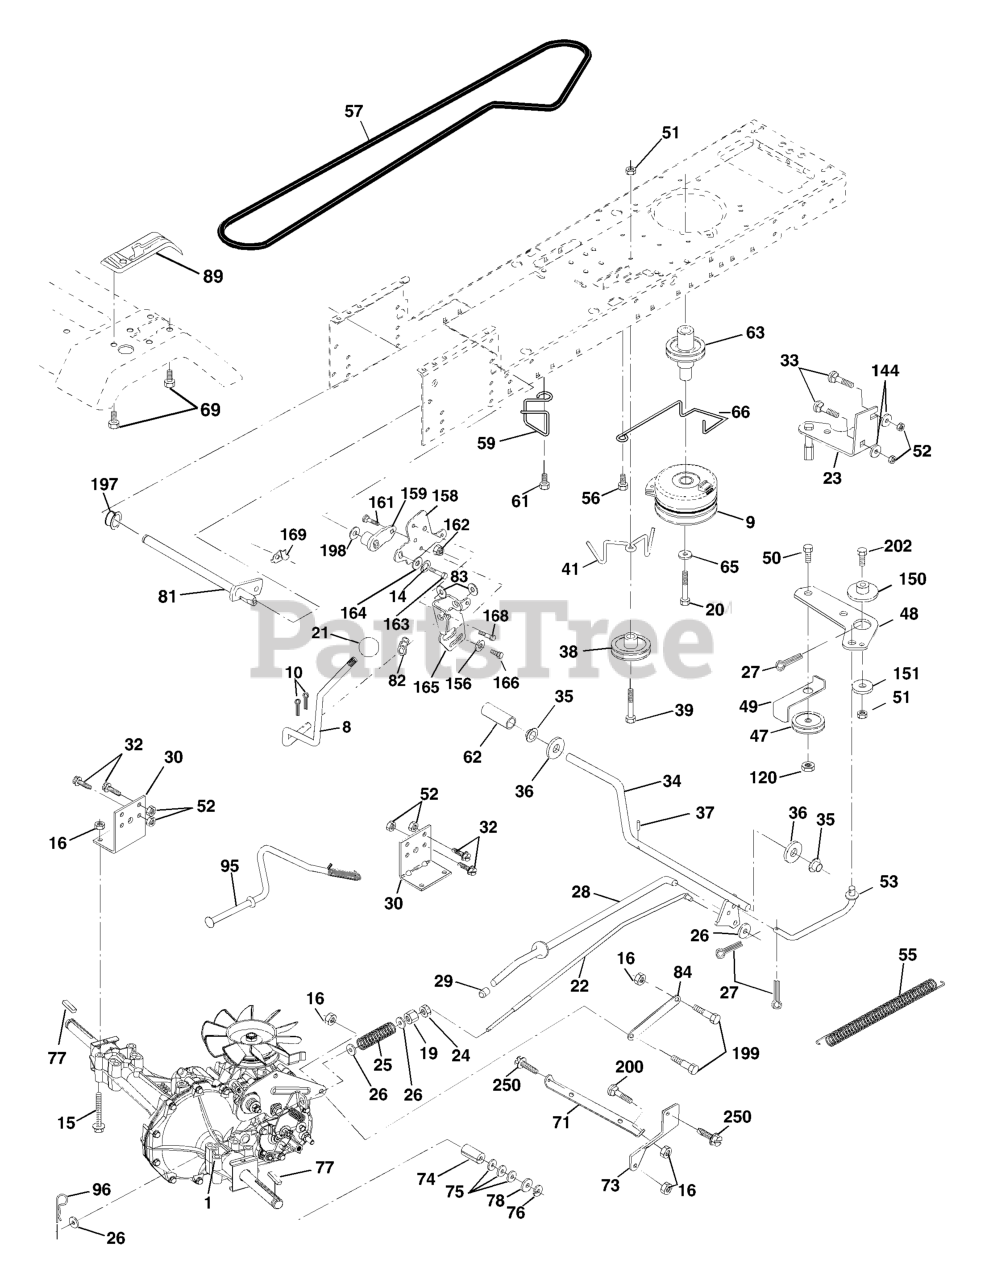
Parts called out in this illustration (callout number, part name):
8	ROD.SHIFT.FENDER.ADJ.LT.CRD
9	CLUTCH.ELECT.EVX.
10	PIN COTTER
14	LOCKWASHER
15	BOLT HEX 5/16-18 GR 5
16	NUT.71038.31-18.HEX.NYLOCK
19	NUT
20	BOLT HEX
21	KNOB.DELUXE.(PISTOL.GRIP).BLAC
22	ROD BRAKE HYDRO
24	NUT
25	SPRING ROD LT
26	WASHER
27	COTTER PIN
28	ROD, PARKING BRAKE
29	PLUNGER CAP
30	BRKT, TRNSXLE MNT 20"
32	BOLT
33	RP BOLT 5/16-18 X3/4 ZN/YEL GR
34	SHAFT, FOOT PEDAL
35	BEARING.NYLON
36	WASHER LT
37	DRIVE PIN
38	PULLEY IDLER COMPOSITE
39	BOLT
41	KEEPER, BELT IDLER
47	IDLER PULLEY
48	BELLCRANK, CLUTCH
49	RETAIN BELT
50	BOLT
52	LOCKNUT
53	LINK, CLUTCH LT
55	SPRING, RETURN LT
56	SCREW.3/8-16
57	DRIVE BELT, LTH & YTH TRACTORS
59	KEEPER, BELT CENTER
61	SCREW 3/8-16X.875
62	PEDAL COVER T
63	PULLEY, ENGINE
65	LOCKWASHER
66	KEEPER BELT ENGINE
69	SCREW.HI-LO.CONSOLE
71	STRAP TORQUE LH HYDRO
73	STRAP TORQUE RH HYDRO
74	SPACER AXLE
77	SQUARE KEY
81	SHAFT ASM CROSS TAPERED
82	SPRING,TORSION
83	WASHER
84	LINK TRANSAXLE
89	CONSOLE, SHIFT
95	CONTROL ASM. BYPASS HYDRO
96	RETAINER M
120	NUT LOCK FLG 3/8-16 UNC
144	Washer 11/32 x 5/8 x 16 Ga.
150	SPACER, RETAINER
151	WASHER 12/32X2X10GA
156	WASHER.SRRTD.5/16
158	BRACKET
159	HUB
161	BOLT
162	NUT.CROWNLOCK.1/4
163	BOLT
164	Washer 5/8 x .281 x 10 Ga.
165	RP BRACKET
168	BOLT.SHOULDER.5/16-18X
169	PLATE.FASTENING.CROSS.SHAFT
197	NYLINER SNAP 5/8" ID
198	WASHER.NYL.7/8IDX.105"HYD CR
199	BOLT SHOULDER 5/16-18 UNC
200	BOLT
202	BOLT.3/8-16X1.50
250	SCREW 3/8-16X3/4
